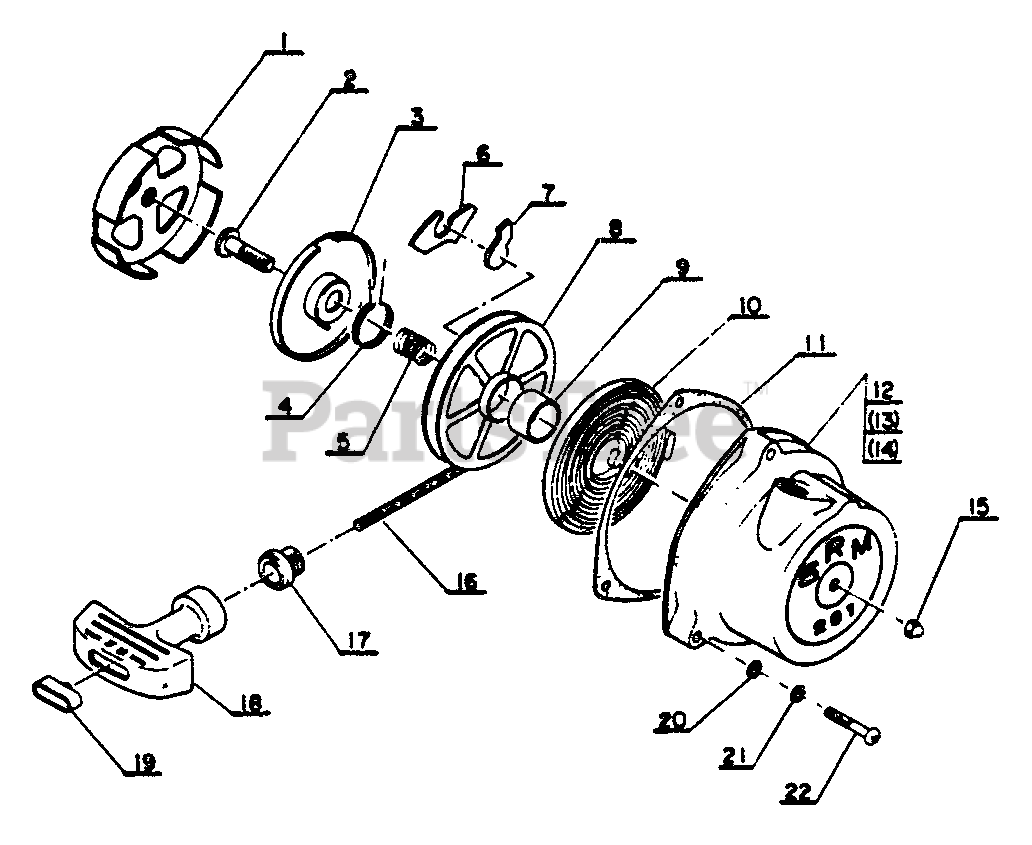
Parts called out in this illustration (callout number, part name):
1	CATCHER, PAWL
2	SCREW, SET
3	RETAINER, RECOIL
4	RETURN SPRING, RECOIL
5	SPRING, RECOIL
6	CAM, RECOIL
7	RATCHET, RECOIL
8	RECOIL DRUM
9	BUSHING, RECOIL
10	SPRING, REWIND
11	CASE, STARTER
12	CASE, STARTER
16	ROPE, STARTER
17	GUIDE, ROPE
18	GRIP, STARTER
19	END PIECE, RECOIL
20	WASHER 4 MM
21	WASHER, SPRING 4 MM
22	SCREW 4×25
